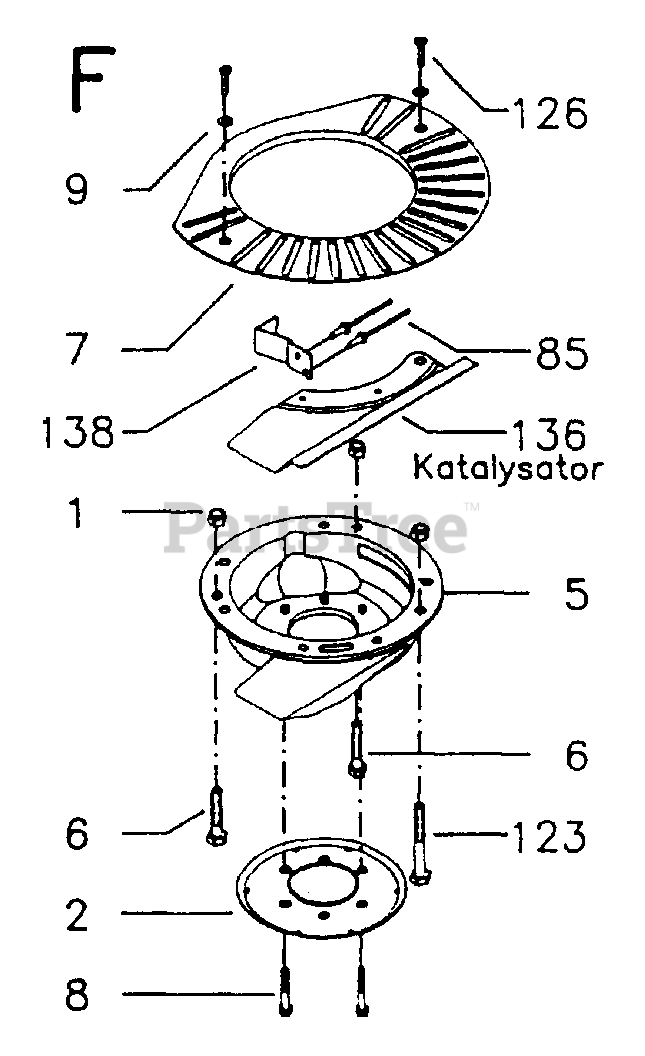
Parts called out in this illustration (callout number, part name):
1	LOCKNUT M8
5	REPL BY 516 69 84-11
7	CENTER PLATE
136	PLATE
